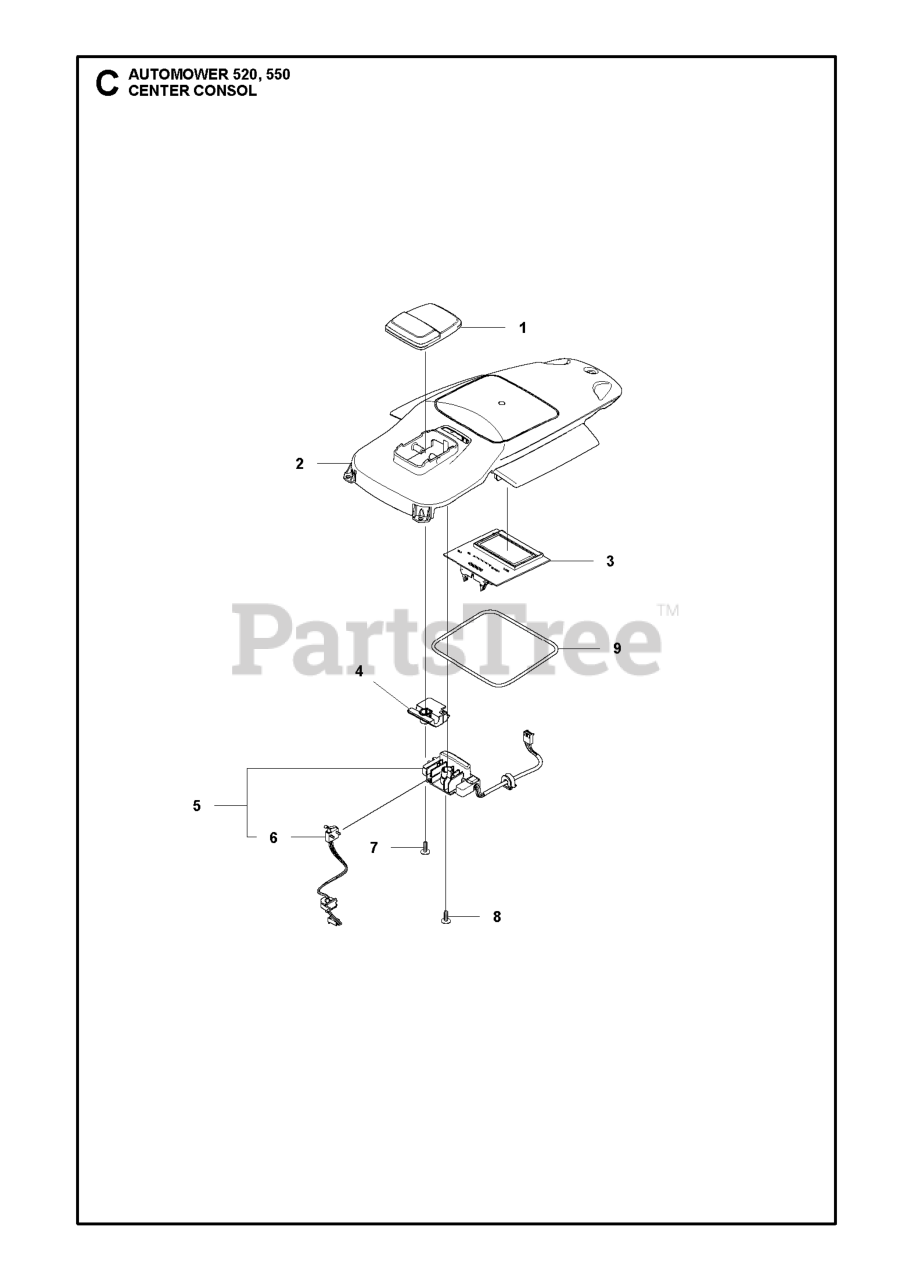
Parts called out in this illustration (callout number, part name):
1	BUTTON STOP
2	CONSOLE CENTER
3	PRINTED CIRCUIT ASSY HMI BOARD
4	SUPPORT BUTTON
5	HOUSING ASSY LED
6	SWITCH STOP BUTTON NO ANCHOR
7	SCREW 14MM
8	SCREW 14MM
9	SEALING STRIP
